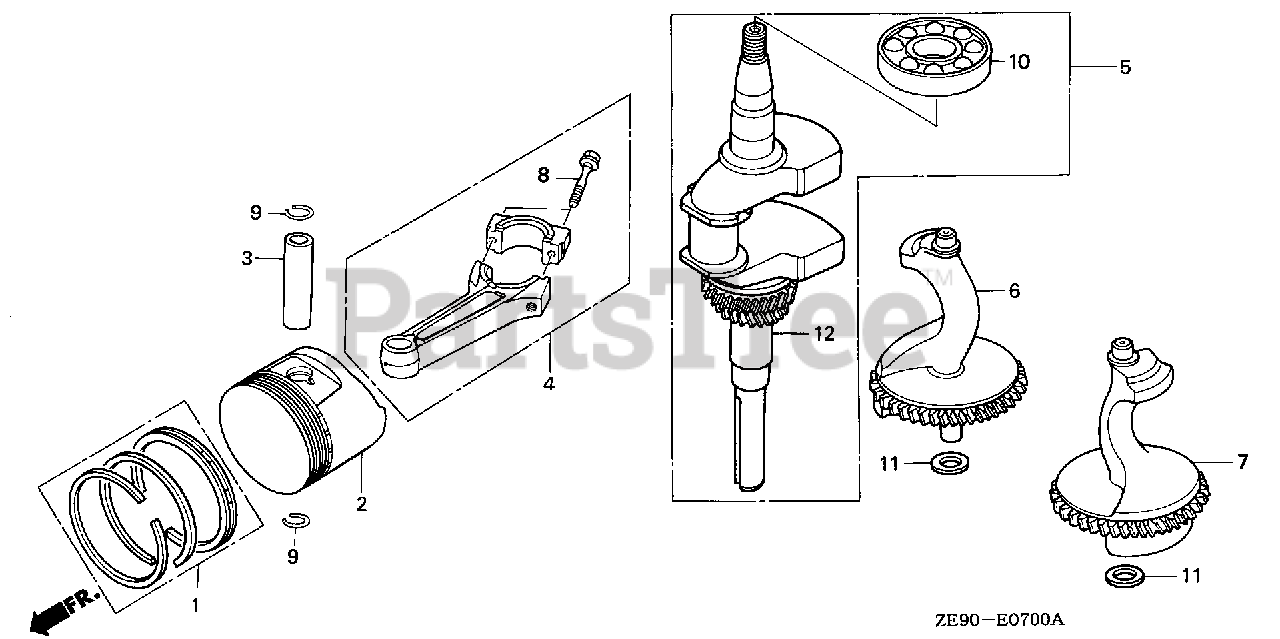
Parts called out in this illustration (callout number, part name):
1	RING SET, PISTON (STD) (NIPPON)
1	RING SET, PISTON (0.25) (NIPPON)
1	RING SET, PISTON (0.50) (NIPPON)
1	RING SET, PISTON (0.75) (NIPPON)
2	PISTON (STD)
2	PISTON (0.25)
2	PISTON (0.50)
2	PISTON (0.75)
3	PIN, PISTON
4	ROD ASSY., CONNECTING (0.25 LOWER SIZE)
4	ROD ASSY., CONNECTING (STD)
5	CRANKSHAFT (NOT AVAILABLE)
6	WEIGHT A, BALANCER (NOT AVAILABLE)
7	WEIGHT B, BALANCER
8	BOLT, CONNECTING ROD
9	CLIP, PISTON PIN (20MM)
10	BEARING, RADIAL BALL (6207)
